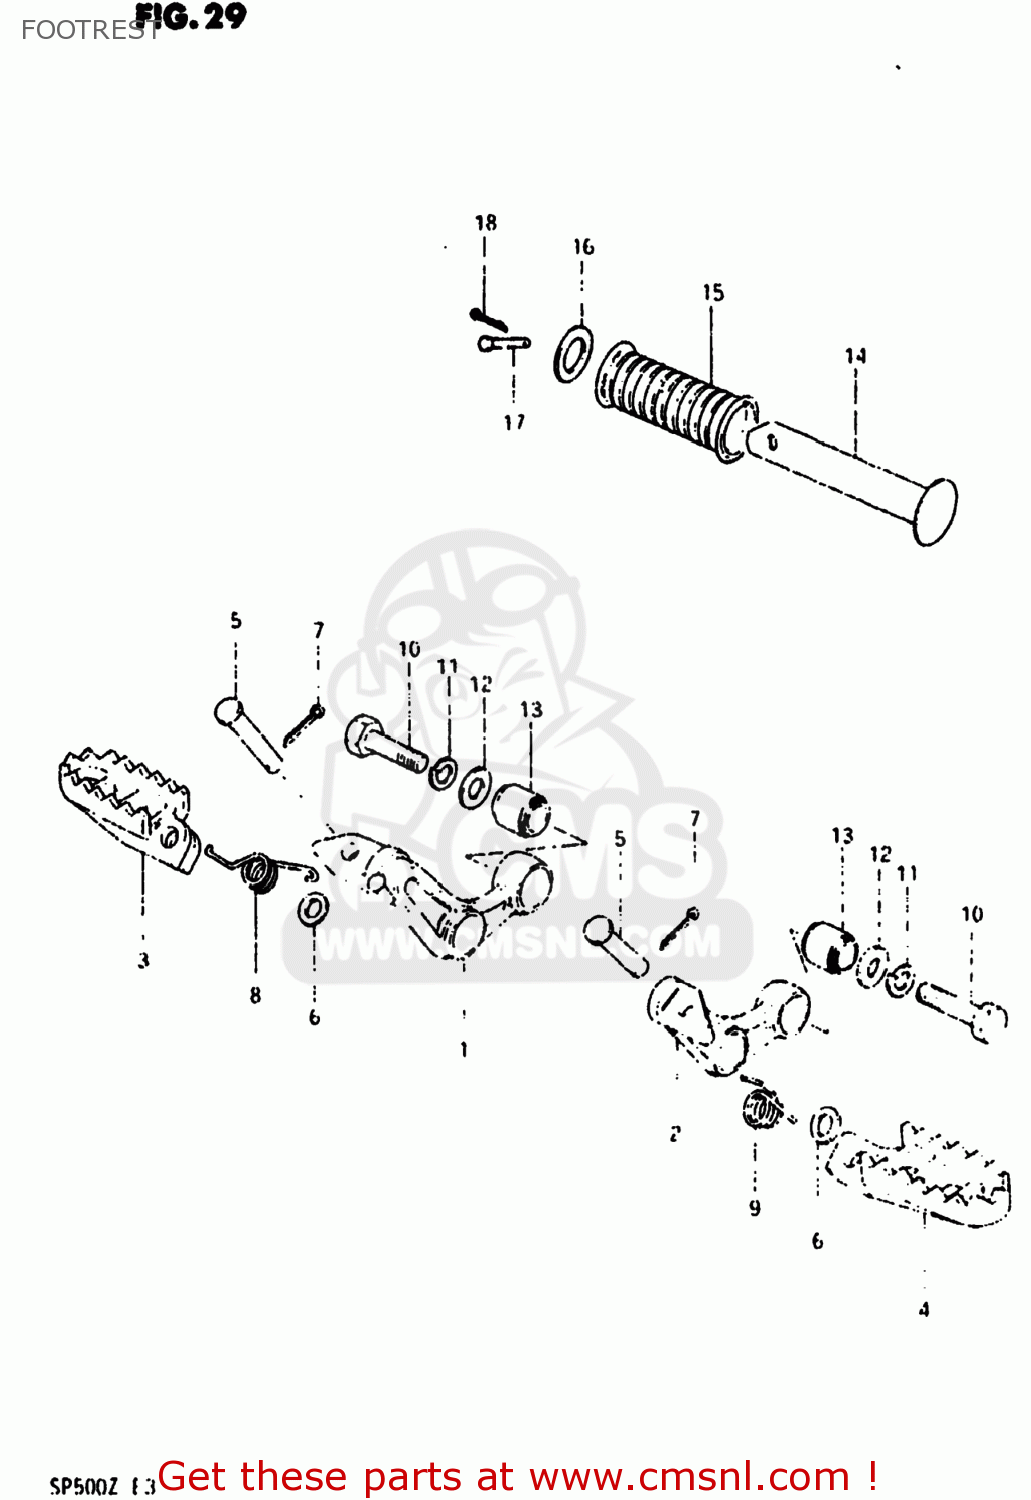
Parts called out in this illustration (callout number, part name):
1	BAR,FRONT FOOTREST
2	BAR,FRONT FOOTREST,LEFT
3	FOOTREST,RIGHT
4	FOOTREST
5	PIN
6	WASHER
7	PIN 20X20
8	SPRING
9	SPRING
10	BOLT
11	LOCK WASHER
12	WASHER (10.1X21X2.3)
13	BUSH
14	BAR,FOOTREST RUBBER
15	RUBBER,PILLION FOOTREST
16	WASHER (19.5X32X2)
17	PIN
18	PIN 20X20
